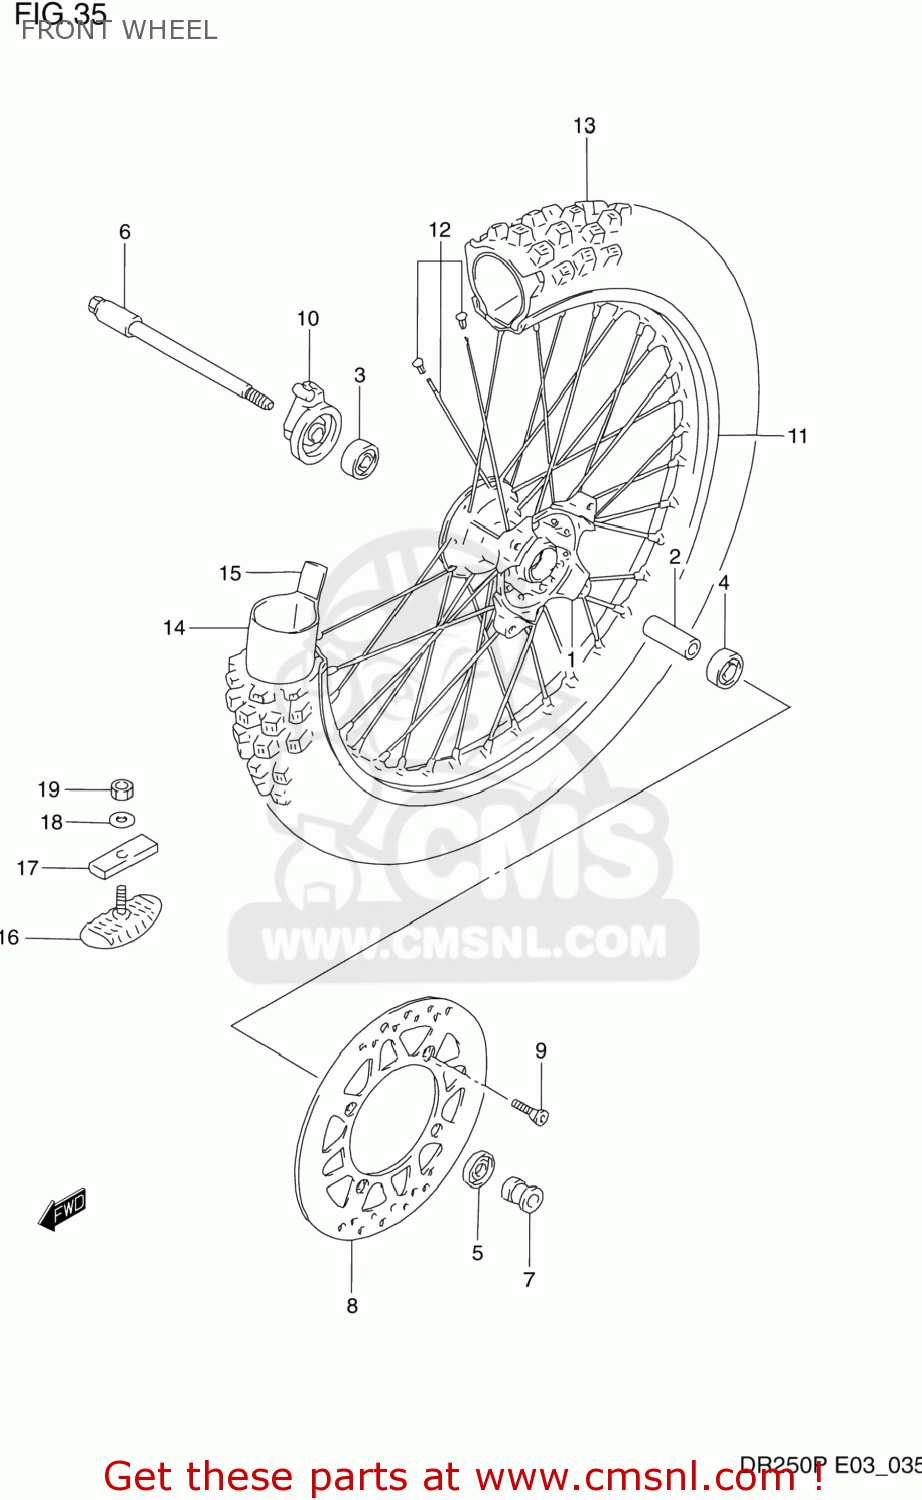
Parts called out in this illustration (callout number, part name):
1	HUB,FR WHEEL
2	SPACER,FR HUB BEARING
3	BEARING
4	BEARING
5	SEAL,OIL(22X35X5)
6	AXLE,FR
7	SPACER,FR AXLE,L
8	DISC,FR BRAKE
9	BOLT,BRAKE DISC
10	BOX ASSY,SPEEDOMETER GEAR
11	RIM,FRONT WHEEL (1.60X2
12	SPOKE SET,FR WHEEL
13	TIRE COMP,FRONT 80/100-21
14	TUBE
15	PROTECTOR,WHEEL,INNER
16	STOPPER,BEAD
17	CUSHION,BEAD STOPPER
18	WASHER
19	NUT 8MM
